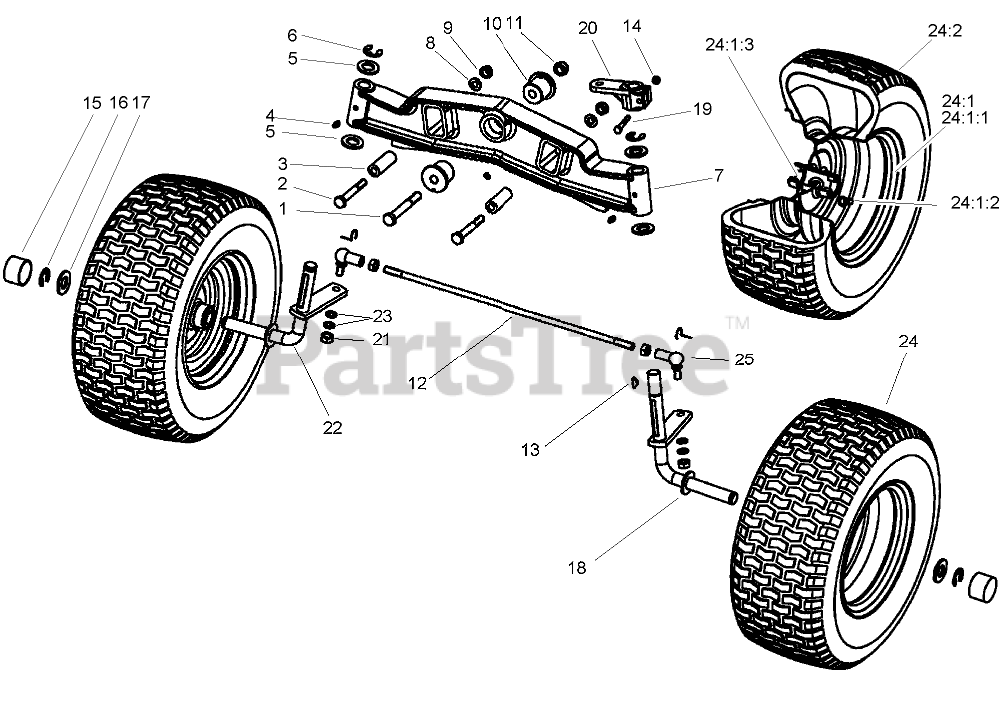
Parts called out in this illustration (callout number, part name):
1	SCREW-HH
2	SCREW-HH
3	SPACER
4	FITTING-GREASE
5	WASHER-FLAT
6	CLIP-SPRING
7	AXLE-FRONT
8	WASHER-FLAT
9	NUT-LOCK, NI
10	BUSHING-AXLE, FRONT
11	NUT-LOCKING, SELF
12	ROD-TIE, FRONT AXLE
13	KEY-WOODRUFF
14	NUT-LOCK
15	CAP-HUB
16	CLIP-SPRING
17	WASHER
18	LH SPINDLE ASM
19	SCREW-HH
20	LEVER-SPINDLE, STEERING
21	NUT-HEX
22	RH SPINDLE ASM
23	Washer
24	WHEEL and TIRE ASM
24:1	WHEEL ASM
24:1:1	RIM
24:1:2	Valve-Tire
24:1:3	BEARING-WHEEL
25	JOINT-BALL, ANGLE
